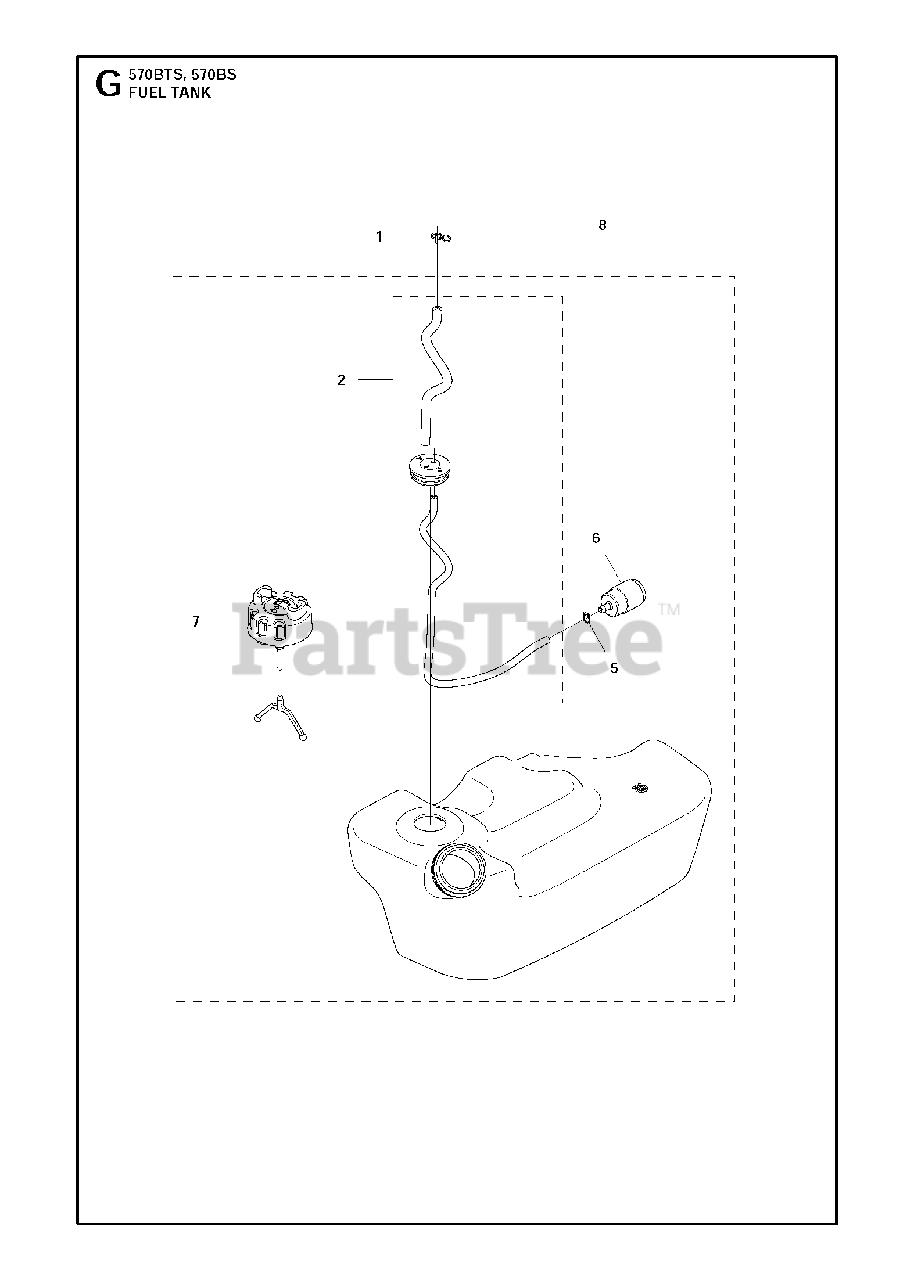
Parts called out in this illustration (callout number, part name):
2	PIPE
5	CLIP
6	FILTER ASSY
7	FUEL CAP ASSY
8	FUEL TANK ASSY
